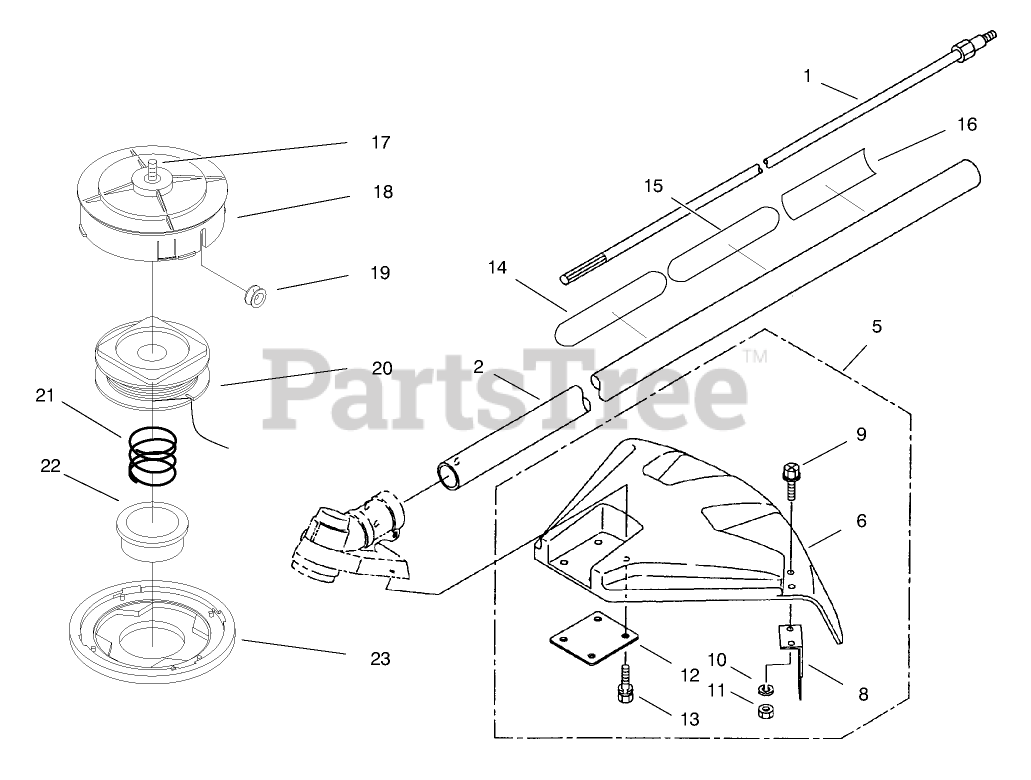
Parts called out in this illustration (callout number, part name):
1	ASM - DRIVESHAFT
2	ASSEMBLY-DRIVESHAFT TUBE
6	COVER - SAFETY
8	CUTTER - STRING
11	NUT M5
14	DECAL - CAUTION
15	DECAL - CAUTION
16	DECAL - TORO
18	HOUSING
19	EYELET
20	SPOOL W/LINE
21	SPRING
22	BUTTON
23	COVER
